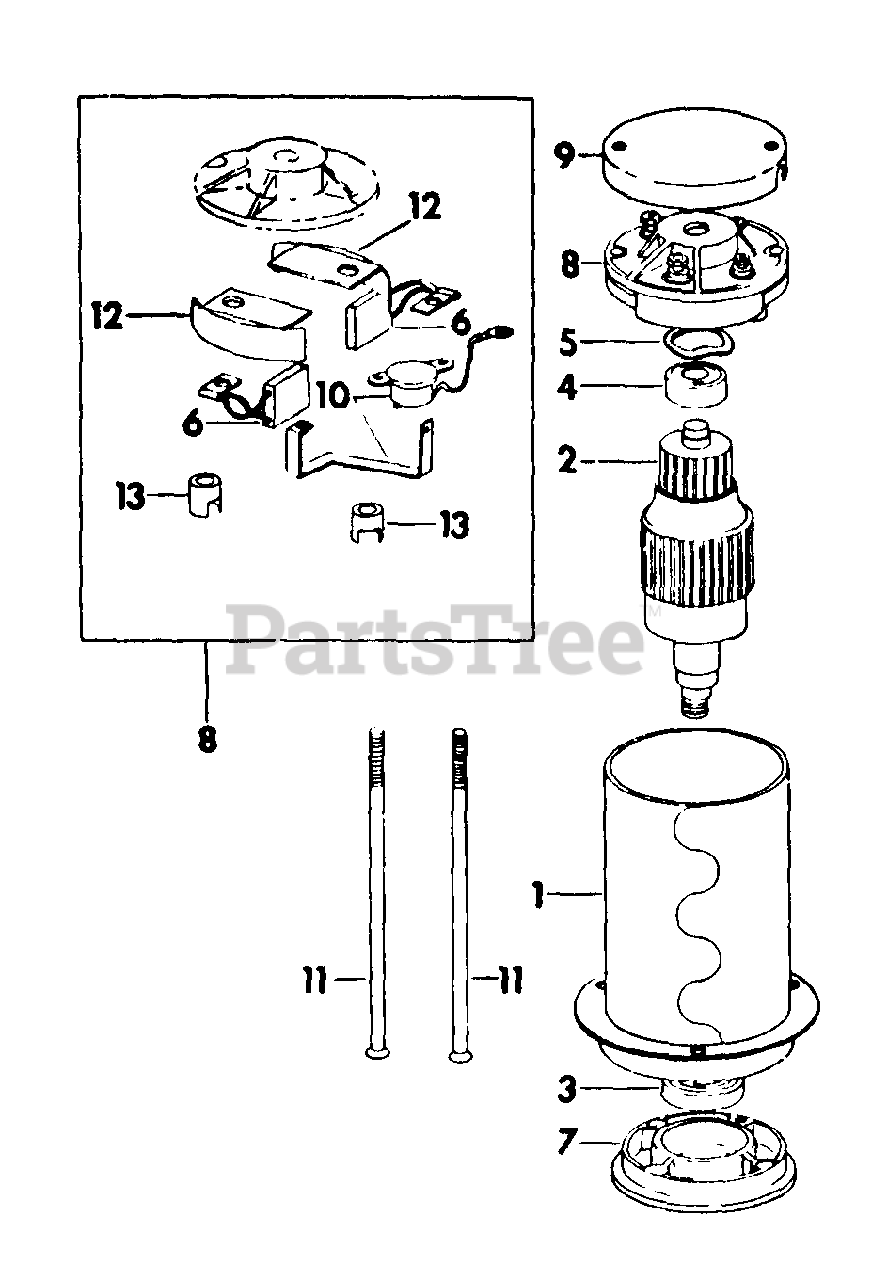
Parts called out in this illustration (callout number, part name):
1	SHELL ASSY W/MAGNETS
2	ARMATURE ASSY W/BRGS
3	BEARING, DRIVE END
4	BEARING, COMMUTATOR END
5	WASHER, WAVE THRUST
7	END, FRT BELL
8	END ASSY, REAR BELL
9	COVER, COMMUTATOR END
10	THERMOSTAT, BRUSH PLATE
12	MOTOR TERMINALS AND INSULATORS PACKAGE
13	SWITCH TERMINALS AND INSULATORS PACKAGE
